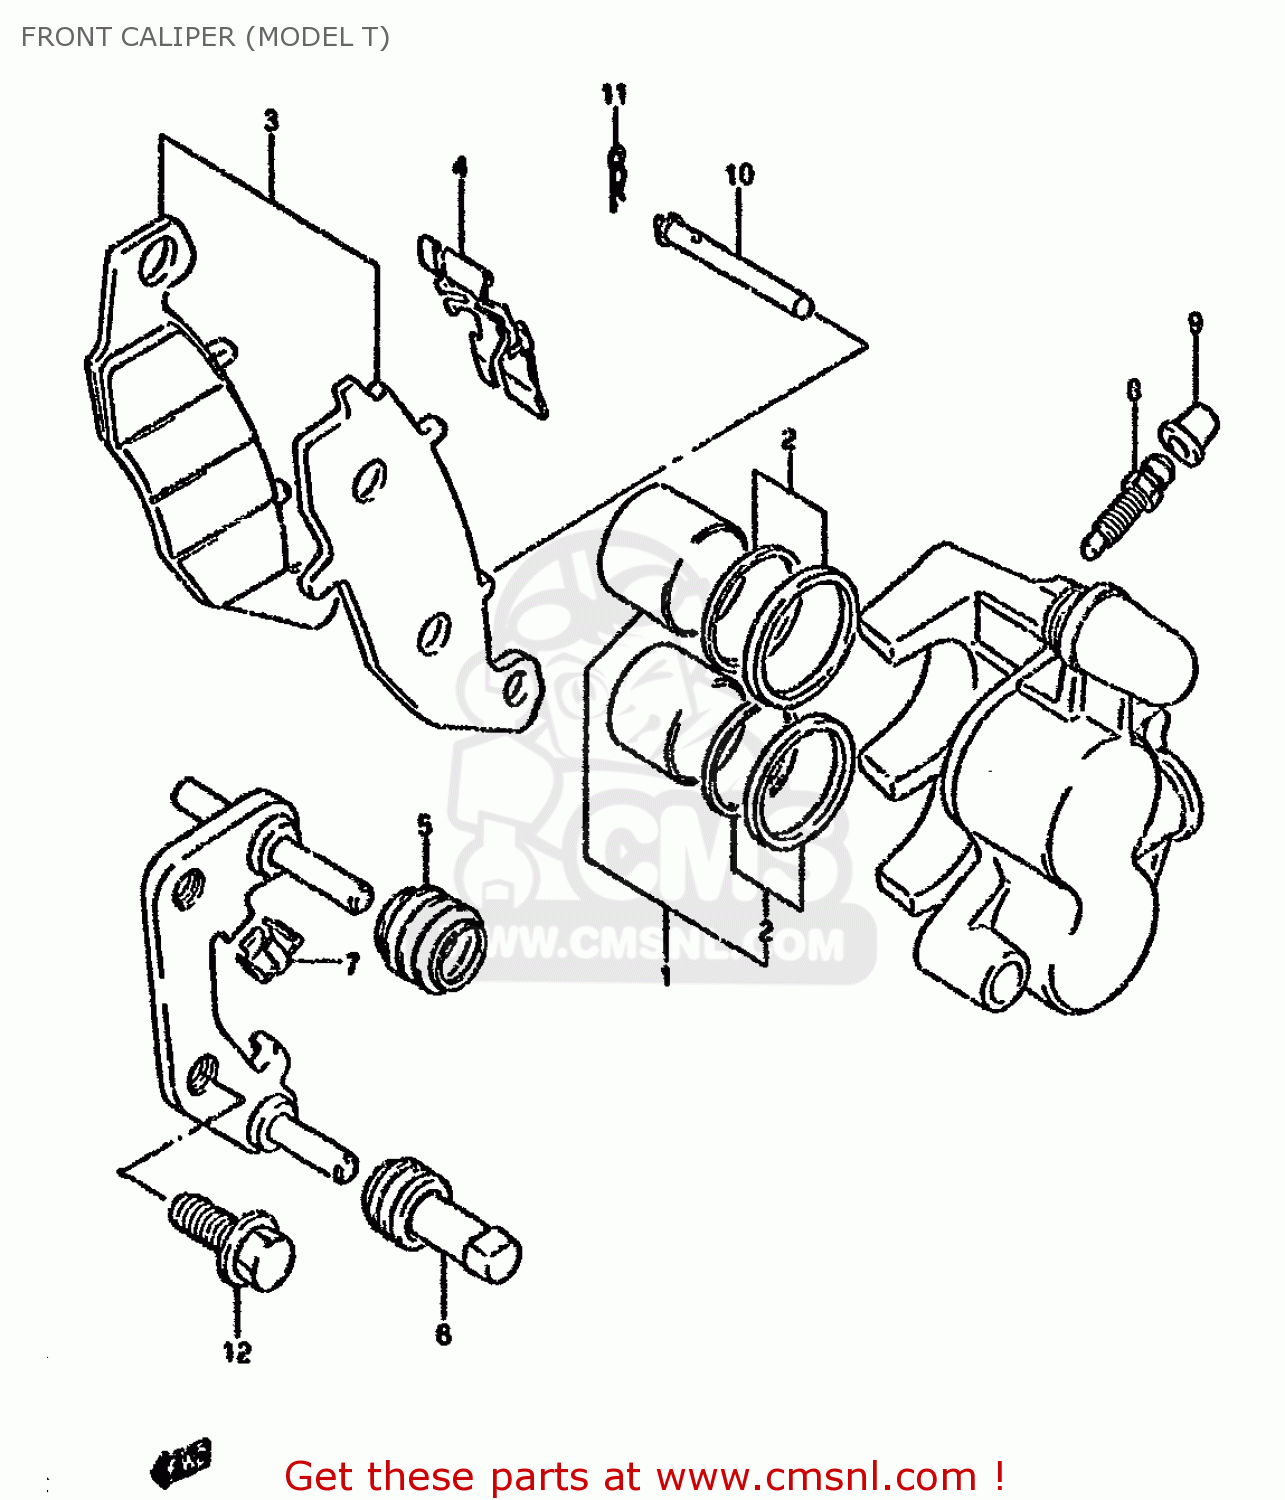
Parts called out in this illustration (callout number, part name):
1	PISTON SET
2	SEAL SET,PISTON
3	PAD SET (NAS)
4	SPRING,PAD,L
5	BOOT,AXLE
6	INSULATOR,AXLE
7	GUIDE,PAD
8	BLEEDER
9	CAP,BLEEDER PLUG
10	PIN,PAD
11	CLIP,PAD PIN
12	BOLT
13	CAP,BLEEDER PLUG
14	BOLT
